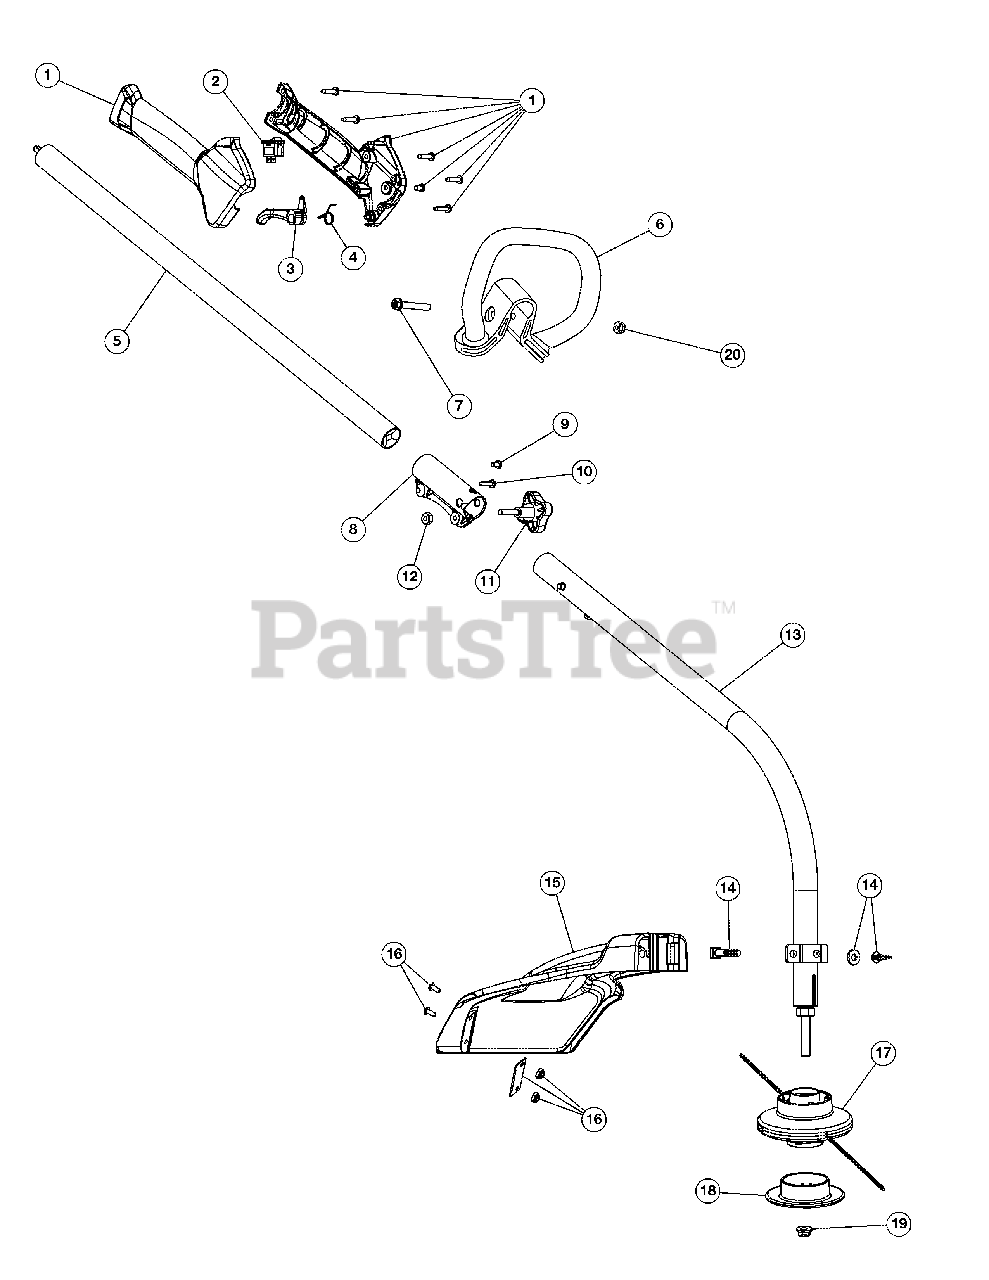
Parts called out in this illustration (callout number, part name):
1	Throttle Housing Assembly (Incl. 2-4)
3	Throttle Trigger
4	Throttle Trigger Spring
5	Upper Shaft Housing Assembly
6	D-Handle (Incl. 7)
7	D-Handle Hardware Assembly
8	Split Boom Coupler (Incl. 9-12)
9	Anti-Rotation Screw
11	Adjustment Knob
12	Knob Retainer Nut
13	Lower Shaft Housing Assembly
14	Shield Mounting Hardware
15	Shield Assembly (Incl. 16)
16	Blade Assembly
17	Cutting Head Assembly (Incl. 18 & 19)
18	Glide Cap
19	Lock Nut
